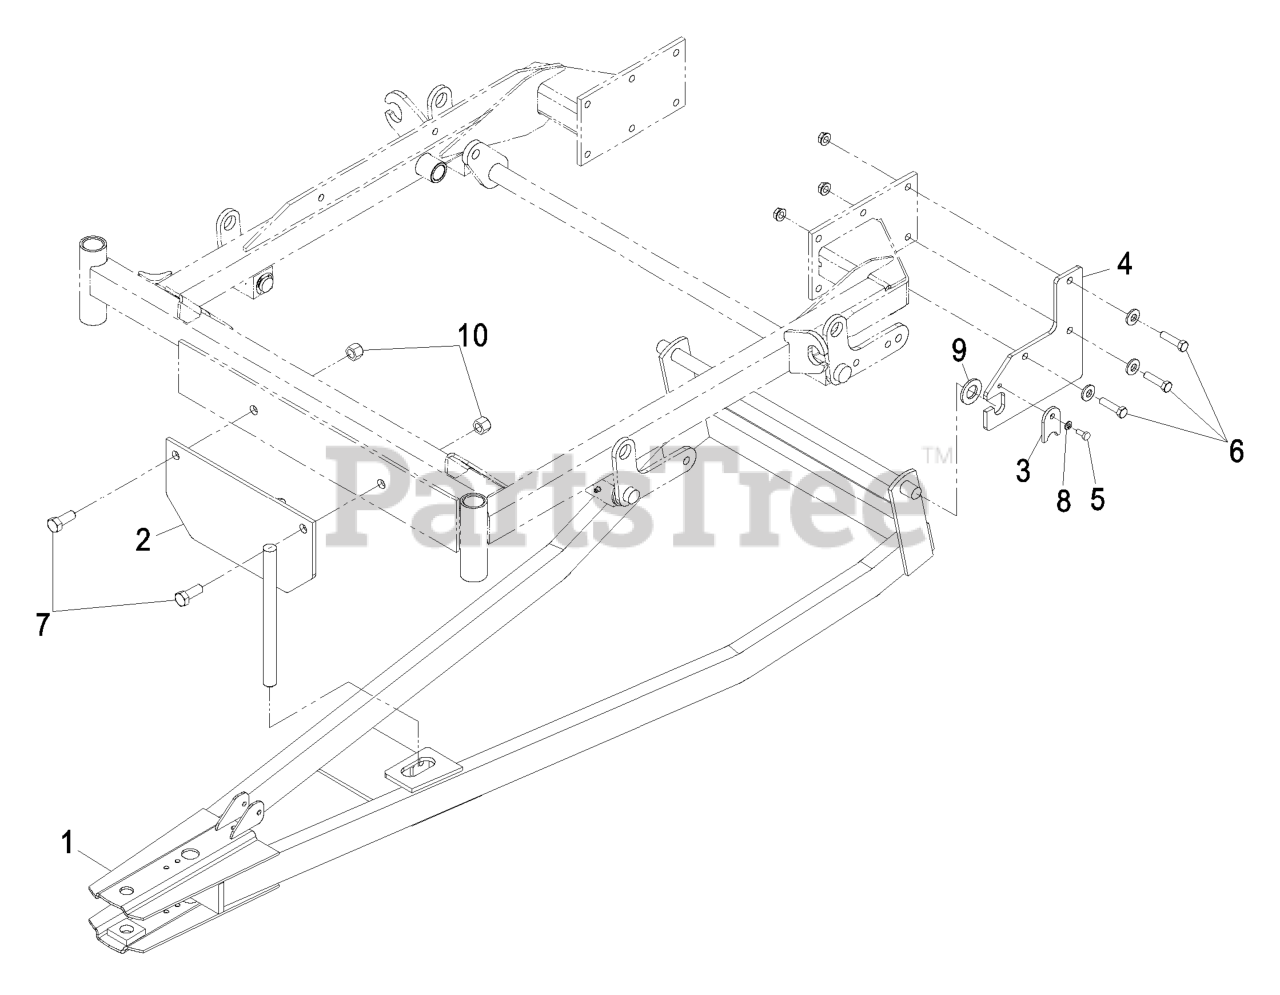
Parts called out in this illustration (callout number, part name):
1	WLD,FRAME-SNOW BLADE
3	PLATE-RETAINER
4	PLATE-SUPPORT
5	SCREW-HH
6	SCREW-HH
7	SCREW-HH
8	SCREW-HH
9	WASHER-FLAT
10	NUT-LOCK, NI
